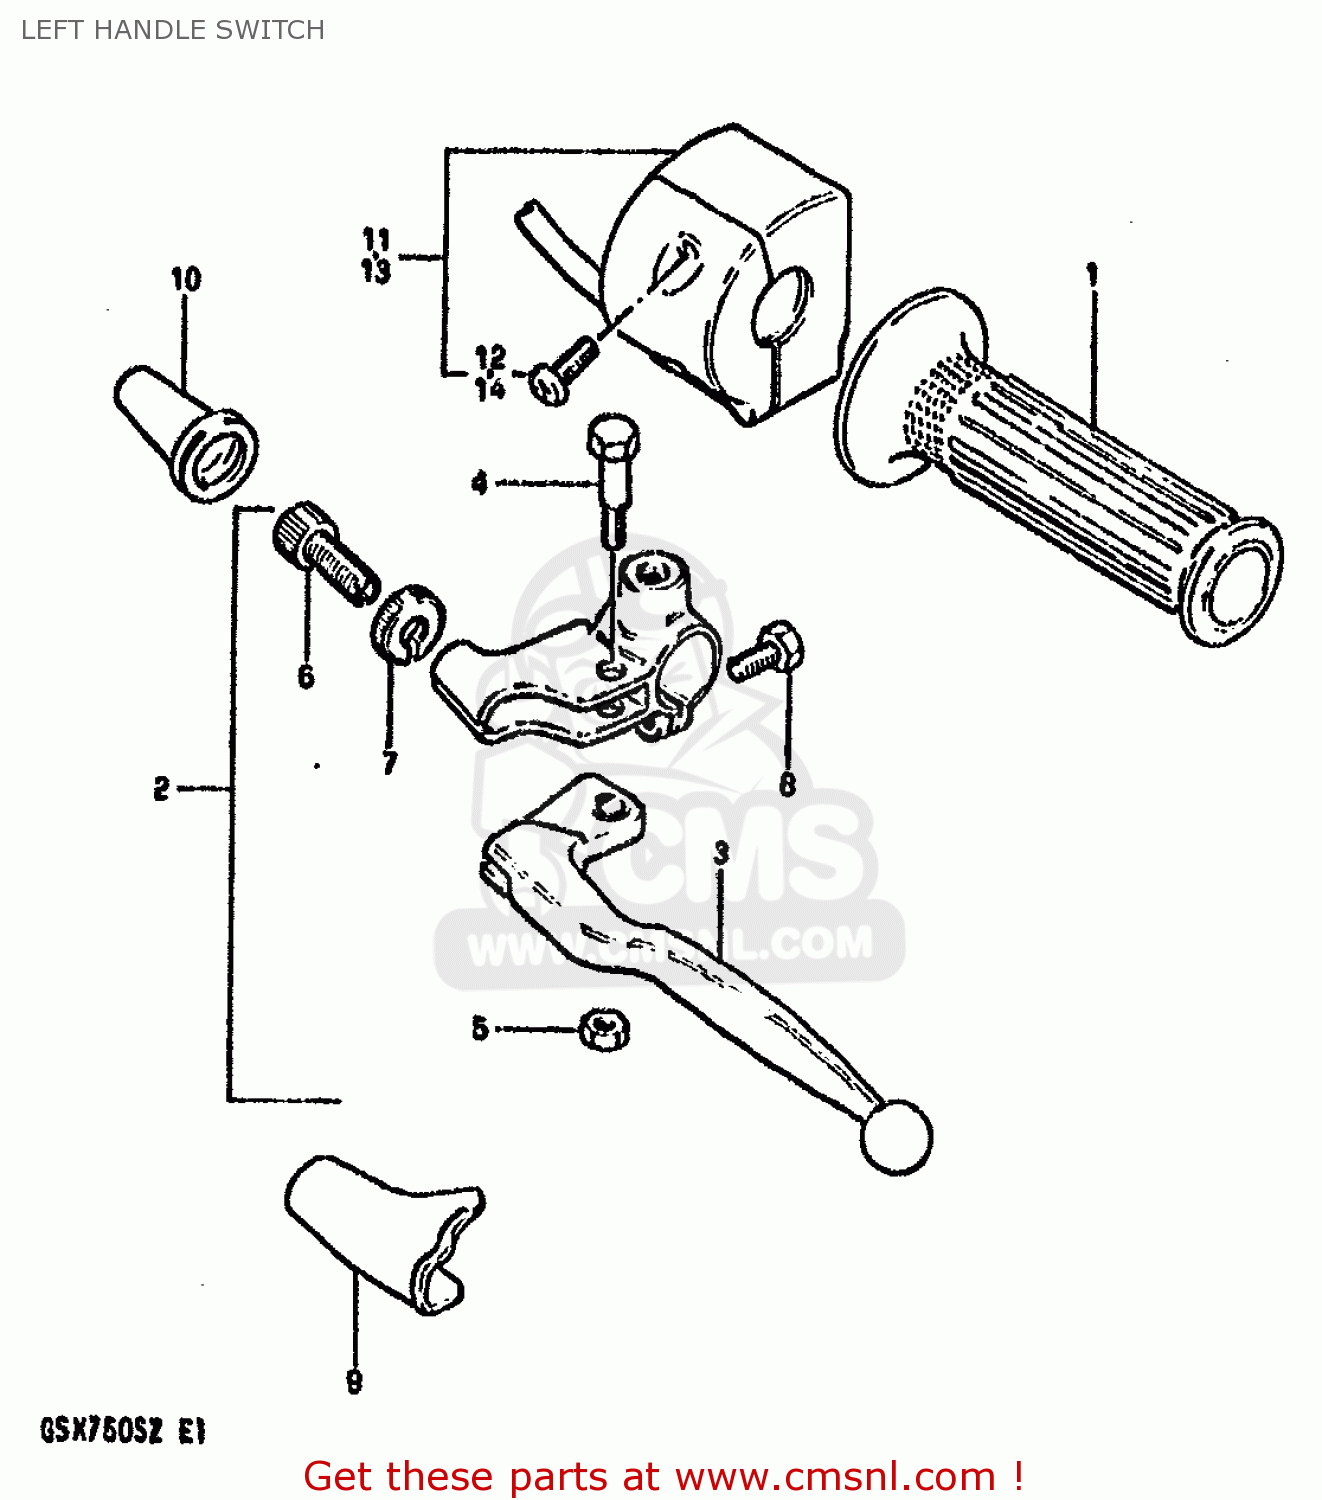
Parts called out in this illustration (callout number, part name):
1	GRIP,LEFT
2	LEVER ASSEMBLY
3	LEVER,CLUTCH
4	BOLT,LEVER
5	NUT 6MM
6	ADJUSTER,CABLE
7	NUT,CABLE ADJUSTER
8	BOLT,CLUTCH LEVER HOLDER
9	COVER,CLUTCH LEVER
10	BOOT,CLUTCH CABLE
11	SWITCH ASSY, HANDLE LH
12	SCREW
13	SWITCH ASSY, HANDLE LH
14	SCREW
